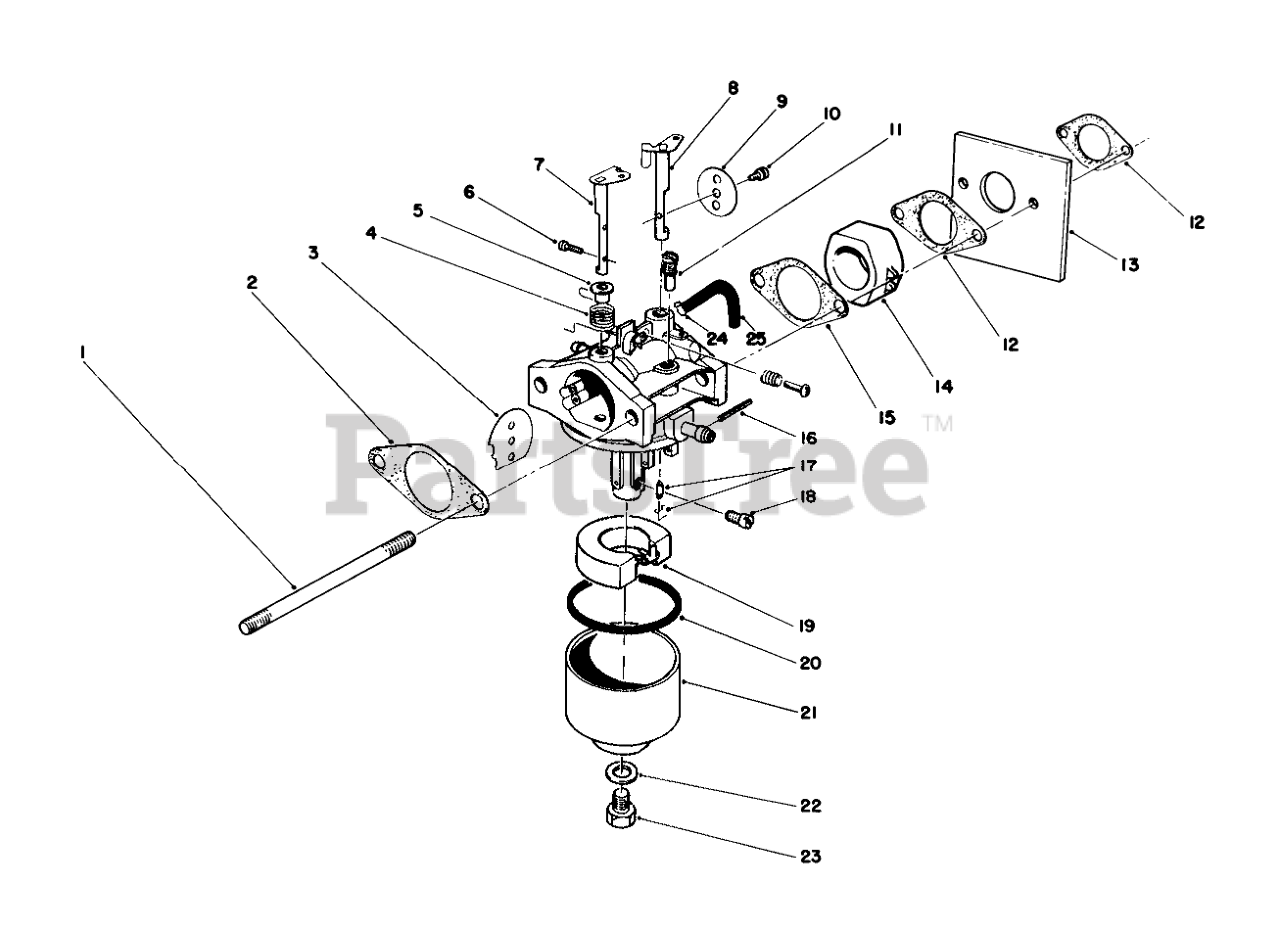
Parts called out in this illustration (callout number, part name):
1	STUD-CARBURETOR
2	GASKET-AIR CLEANER
3	PLATE
4	SPRING
5	BUSHING
6	SCREW
7	SHAFT-CHOKE
8	SHAFT
9	PLATE
10	Screw-Throttle
11	PILOT JET
12	GASKET
13	SHIELD-CARBURETOR
14	INSULATOR-CARBURETOR
15	GASKET-CARB
16	Pin
17	NEEDLE
18	JET-MAIN
19	FLOAT
20	GASKET
21	Bowl-Float
22	GASKET
23	Bolt
24	CLAMP
25	VENT TUBE
